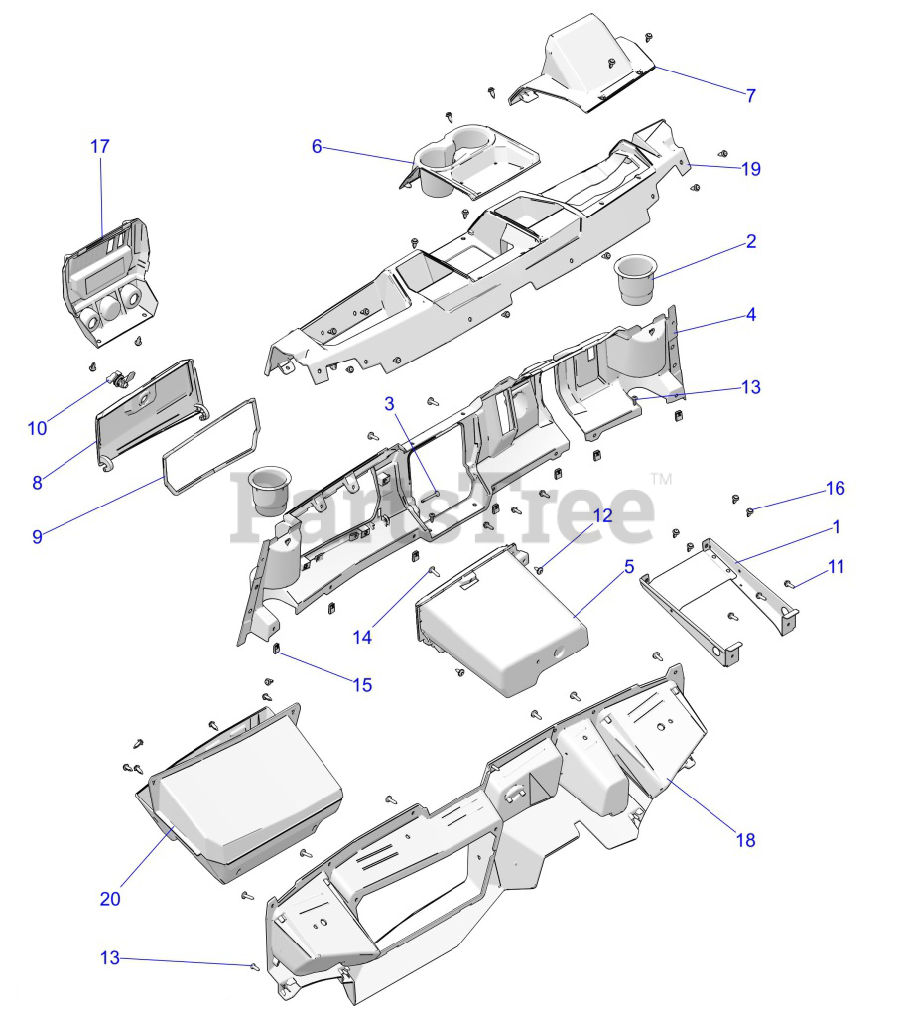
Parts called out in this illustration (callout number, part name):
1	WELD-DASH SUPPORT,BLK
2	HOLDER-CUP
3	PIN-HINGE-GLOVEBOX
4	DASH-MAIN-BLK
5	BIN-GLOVEBOX-BLK
6	DASH-CENTER TRAY-BLK
7	DASH-GAUGE BEZEL-BLK
8	COVER-BOX-GLOVE-BLK
9	SEAL-GLOVEBOX-897
10	LATCH-1/4 TURN- CAM
11	SCR-M6X1.0X20-HXHD-FLG-TDFM-BL
12	SCR-M6X1X16 TR/TX-M
13	SCR-TX TRUSS-#14X3/4-HI/LO ZBK
14	SCR-TXTH-M6X1.0X25 RIE
15	NUT-M6-1.0- U-TYPE (2.5-3.8)
16	RIVET-TUFLOK-.315-.325X.787 (5
17	DASH-CONTROLS,ROUTER,BLK
18	DASH-STORAGE-BLK
19	DASH-UPPER-BLK
20	BIN-LOWER-STORAGE-BLK
